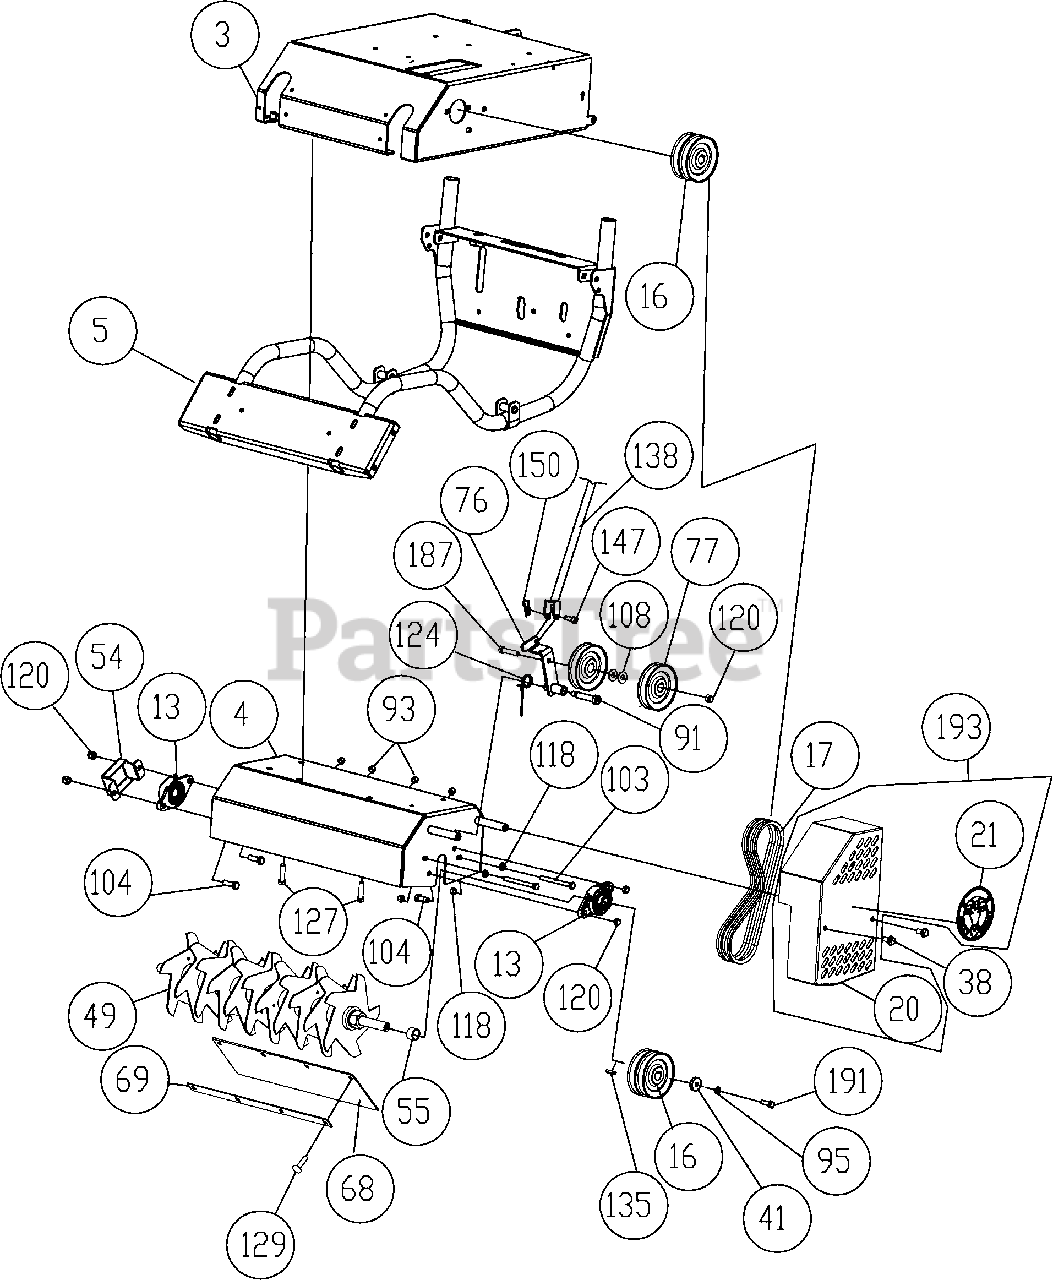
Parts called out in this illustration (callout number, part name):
3	ENGINE BASE WA
4	HOUSING VERTICUTTER WA OS900SP
5	FRAME SUPPORT OS900SP WA
13	BEARING 3/4" CAST FLANGE W/ZERK
16	PULLEY 0.75" ID X 4" 4L SECTION
20	GUARD REEL BELT OS900SP
21	LABEL DECAL SM CIRCLE
38	SER HEX WASHER 3/8" - 16
41	WASHER 1.125 OD X .344 ID X 10 GA
49	REEL ASSY OS900SP
54	GUARD BEARING REEL OS900SP
55	SPACER SEED BOX AXLE OS900SP
68	DEFLECTOR RUBBER OS900SP
69	BAR CLAMP DEFLECTOR
76	ARM IDLER WA REEL ENGAGE
91	BOLT SHOULDER 1/2" X 2"
93	NUT LOCK 5/16"-18
95	WASHER SPLIT LOCK
103	SCREWCAP 5/16-18 X 3 1/2"
104	SCREWCAP 3/8"-16 X 1"
108	WASHER 5/16" FC
118	NUT FLANGE 5/16-18 ZP
120	NUT LOCK 3/8-16 LT WT THIN ZP
124	SPRING IDLER MULE DRIVE
127	SER HEX WASHER FLNG SCREW 5/16"-18 X 3/4"
129	BOLT CARRIAGE 5/16"-18 X 3/4" ZP
135	KEY 3/16" SQ X 1 1/4"
138	CABLE CLUTCH SEEDING CONTROL
147	PIN CLEVIS 1/4" X .50"
150	PIN CLIP HITCH 0.051" X 3/4"
187	SCREWCAP 3/8"-16 X 2 1/2" ZP
191	SCREWCAP 5/16"-24 X 1" GR.8 ZP W/PATCH
193	GUARD REEL BELT OS900SP W/LABELS
